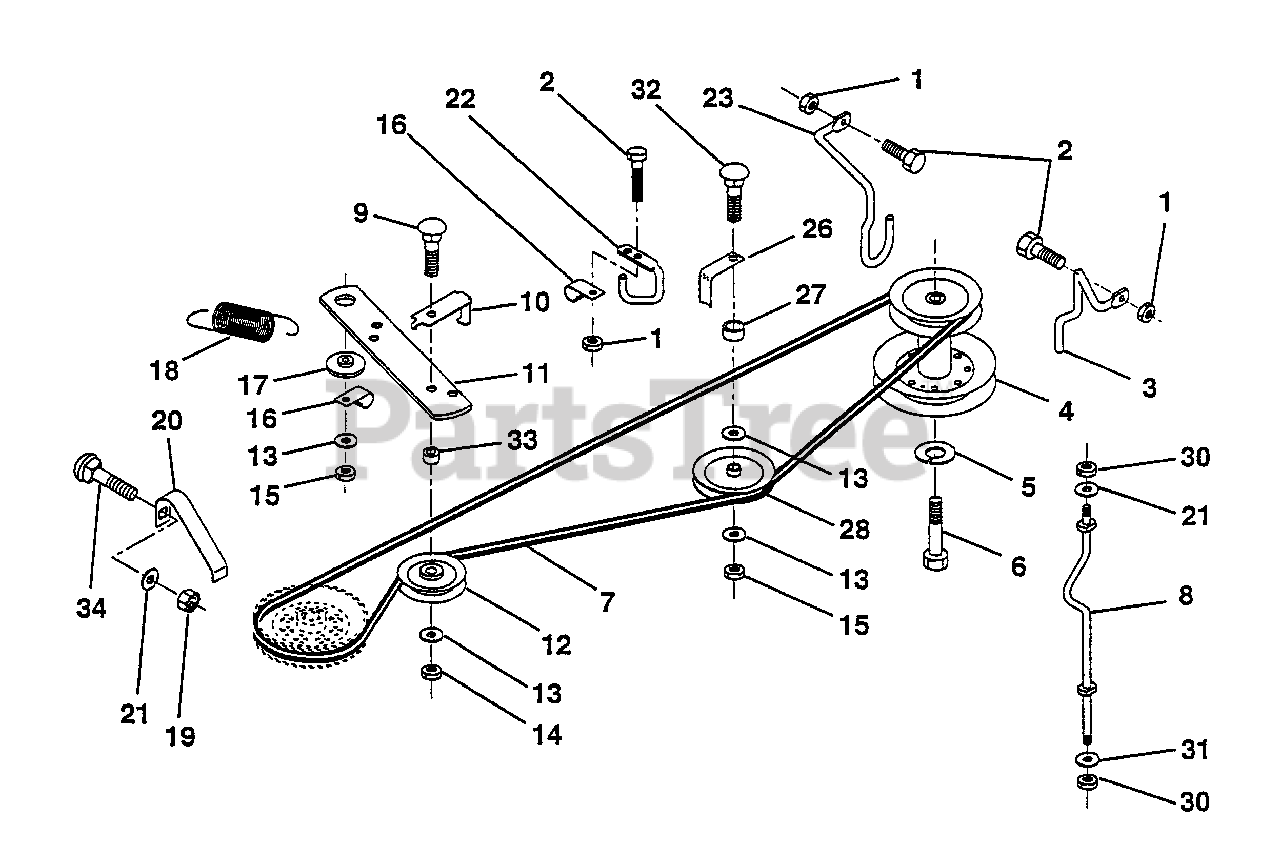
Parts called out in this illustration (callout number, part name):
1	Nut, Lock Hx w/Ins 5/16-18
2	Bolt, Hex Head 5/16-18 x 3/4
3	Keeper, Belt RH Front
4	Pulley, Engine
5	Washer, Lock 7/16
6	Bolt, Hex Fin M10 x 1.5 x 75mm
8	Keeper, Belt RH
9	Bolt, RDHD SQ 3/8-16 x 2-1/4
10	Keeper,Belt, Idler Pulley
11	Arm, Idler
12	Idler, Flat
13	Washer 13/32 x 13/16 x 16 Gauge
14	Nut, Centerlock 3/8-16
15	Nut, Hex, Lock Hex w/wsh 3/8-16
16	Clip Insulator
17	Spacer, Retainer
18	Spring, Extension
20	Keeper,Belt LH
21	Washer Nut Lock Hex w/Ins. 5/6-18
22	Keeper Frame Ground Drive Belt
23	Keeper,Belt LH Front
26	Keeper, Belt
28	Pulley, V-Idler
30	Nut Lock Hex w/Ins. 5/16-18
31	Washer 11/32 x 3/4 x 16 Ga.
32	Carriage Bolt
34	Carriage Bolt
